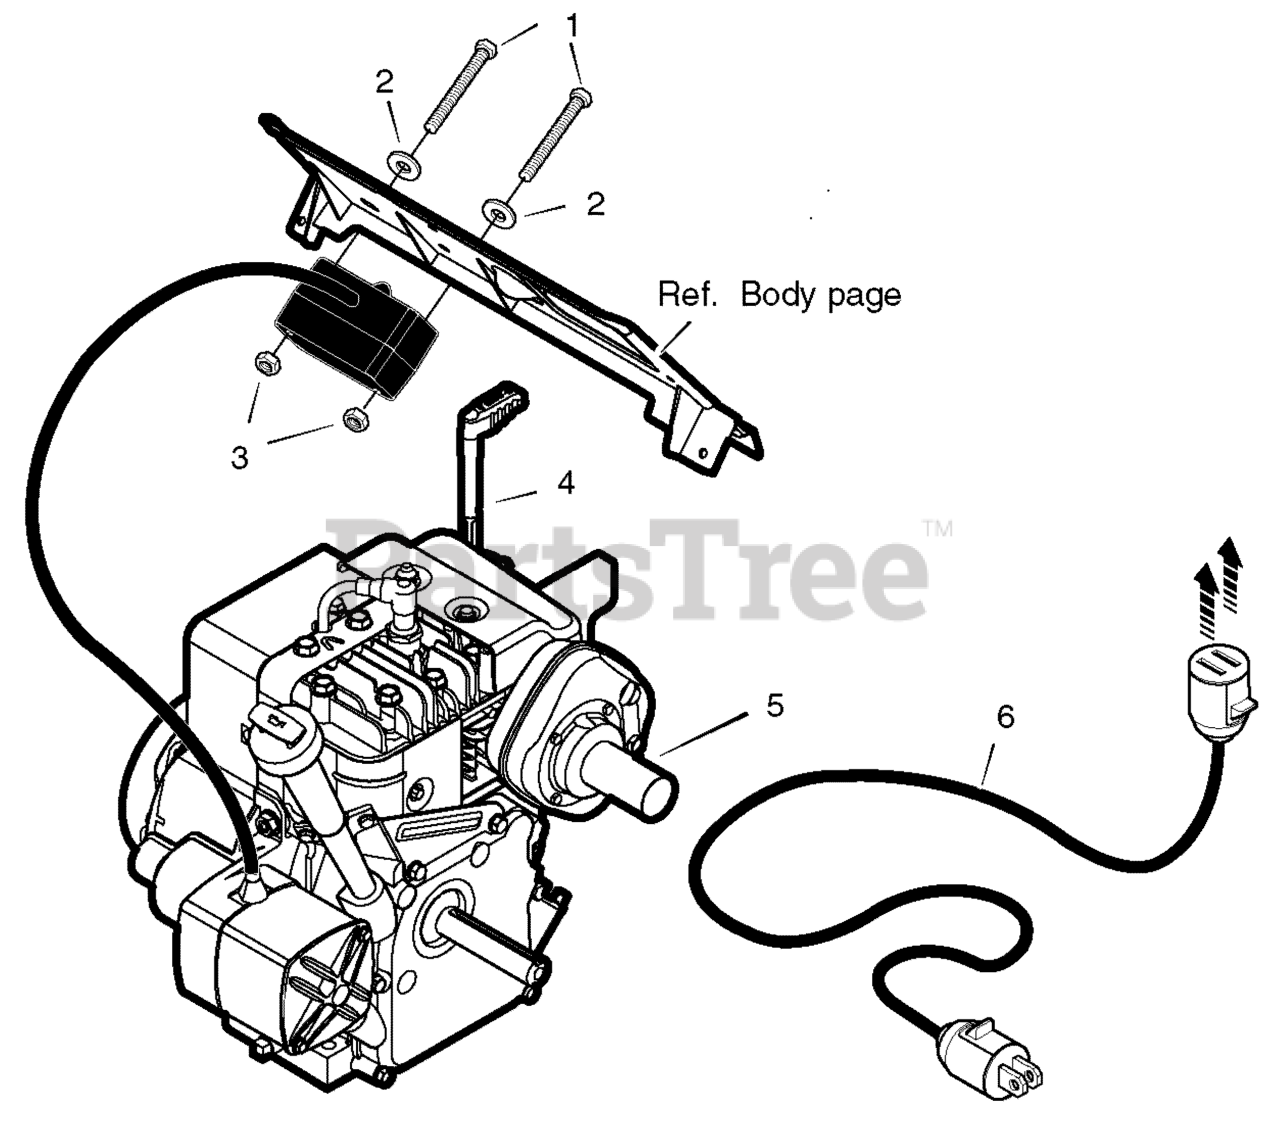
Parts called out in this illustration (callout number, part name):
1	Screw, No. 8-32 x 3.00
2	Washer
3	Nut, Keps No. 8
4	Lever, Choke *
5-1	Muffler *
5-2	Gasket, Muffler *
5-3	Bolt, Muffler *
5-4	Washer, Split Lock
5-5	Nut, Hex 5/16-18
5-6	Bolt, Hex 5/16-18
6	Cable, Starter
